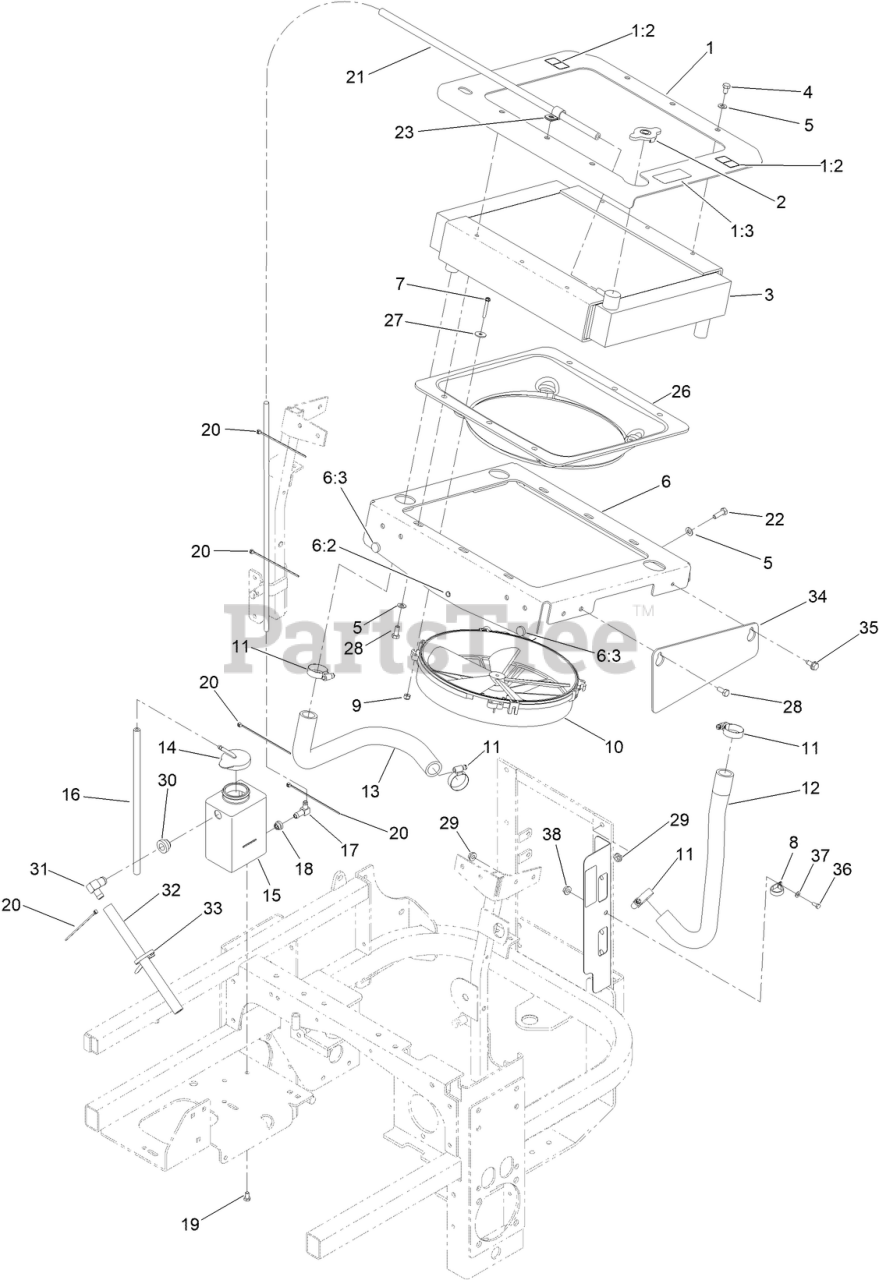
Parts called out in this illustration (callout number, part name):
1	TOP RADIATOR PLATE ASM
1:2	DECAL-SURFACE, HOT
1:3	DECAL-ANTIFREEZE
2	CAP-RADIATOR
3	RADIATOR
4	SCREW-HH
5	WASHER-PLAIN
6	BOTTOM RADIATOR PLATE ASM
6:2	NUT-CLINCH
6:3	BUMPER
7	SCREW-HWH
8	CLIP-LOOM
9	NUT-LOCK, HH
11	CLAMP-HOSE
12	HOSE-RADIATOR, LH
13	HOSE-OUTLET, ENGINE
14	CAP-TANK, OVERFLOW
15	TANK-OVERFLOW
16	HOSE-LINE, FUEL
17	FITTING-ELBOW, 90 DEG
19	SCREW-HH
20	TIE-CABLE
21	HOSE-OVERFLOW
22	SCREW-HH
23	CLIP-LOOM
26	SHROUD-COOLING, ENGINE
27	WASHER
28	SCREW-HH
29	NUT-HF
31	FITTING-ELBOW
32	HOSE-OVERFLOW
33	TIE-CABLE
34	SHIELD-RADIATOR
35	SCREW-HWHTF
36	SCREW-HH
37	WASHER-FLAT
38	NUT-HF
